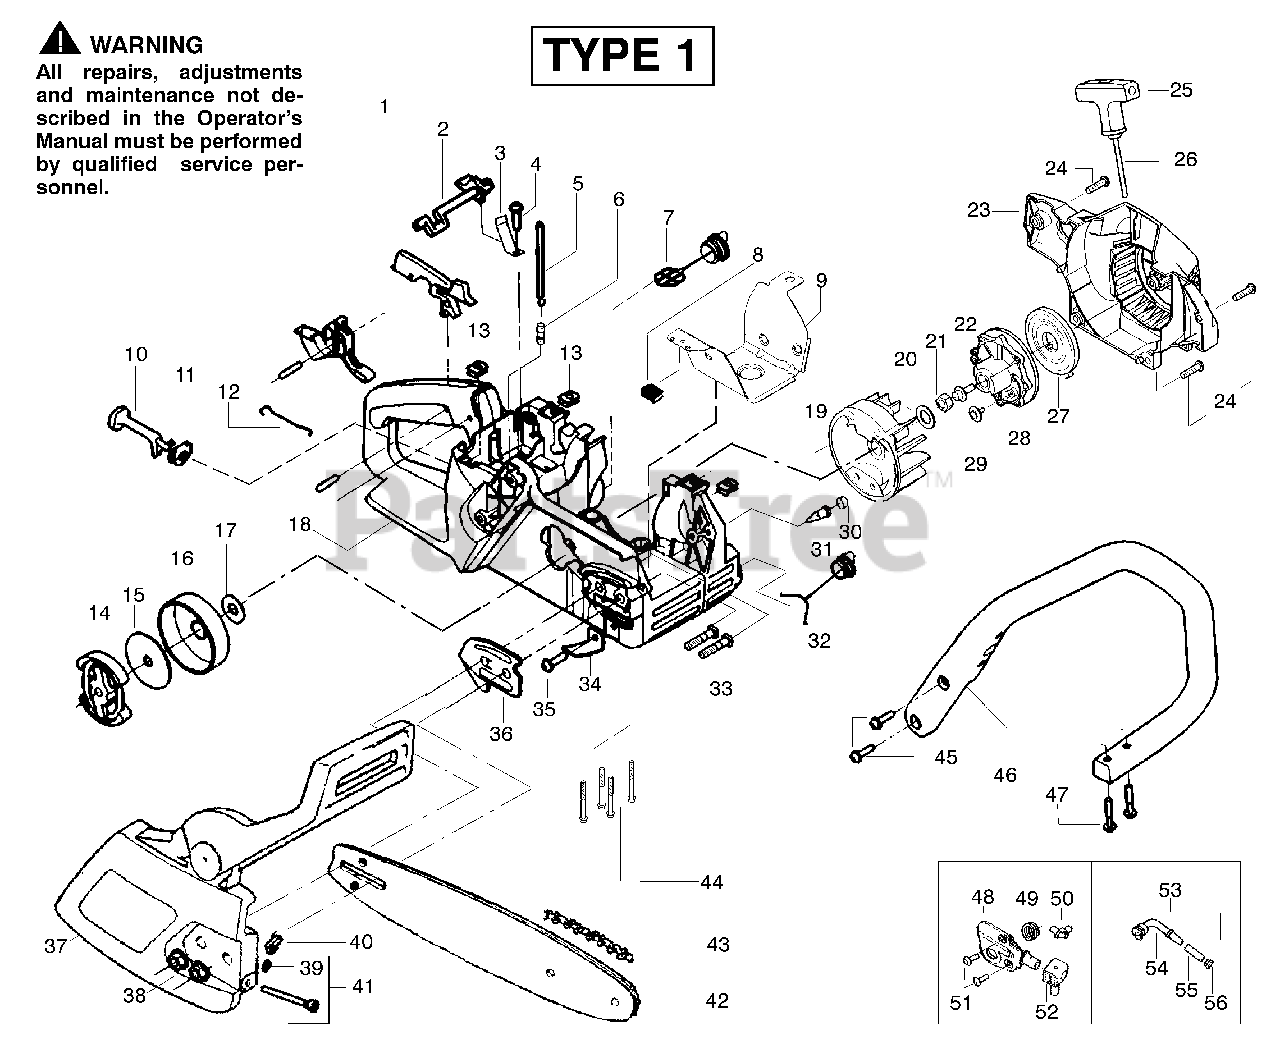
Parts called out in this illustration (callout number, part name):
1	Kit-Trigger & Lockout
2	Lever-Switch
3	Spring-Switch
5	Kit-Fuel Line
6	Fitting - Fuel Line
7	Assy-Fuel Cap W/ret.
8	Clip - "U"
9	Shield - Heat
10	Lever-Choke
11	Grommet-Choke Lever
12	Wire-Throttle
13	Nut-Speed
14	Assy.-Clutch
15	Washer-Clutch
16	Assy-Drum W/brg.
17	Washer - Thrust
18	Kit - Chassis Assy.
19	Assy-Flywheel
20	Washer-Flywheel
21	Nut-Flywheel
23	Housing-Fan
25	Handle-Starter
26	Kit-Rope
27	Spring-Starter
28	Pulley-Starter
30	Plug - Bronze Vent
31	Check Valve
32	Assy-Oil Cap
33	Bolt - Bar
34	Chain Catcher
36	Plate-Bar Mounting
37	Assy.-Chain Brake
38	Nut-Bar Mounting
39	Retainer-Bar Adjust
40	Pin-Bar Adjust
41	Kit-Bar Adjust
43	Chain-14"
46	Handle-Front
48	Kit-Oil Pump
49	Gear-Worm Spring
50	Elbow-Oil Pickup
52	Block-Seal
53	Assy-Oil-Pickup
54	Pickup-Oiler
55	Filter-Oil
56	Plug-Oil Filter
